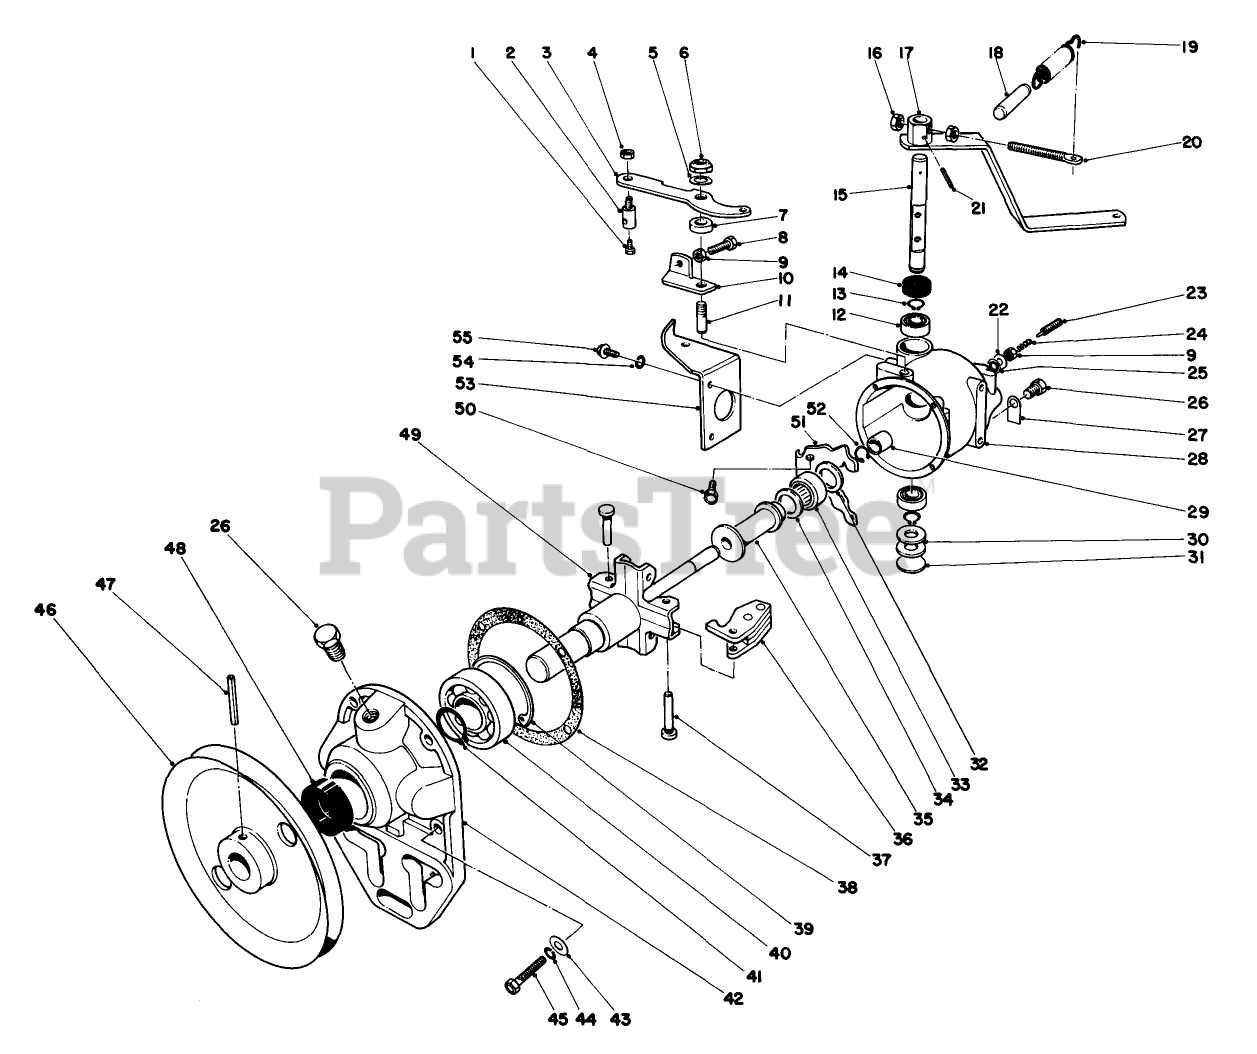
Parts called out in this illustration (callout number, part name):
1	SCREW-HH
2	SWIVEL
3	Speed Change Lever
4	NUT-LOCK, NI
5	WASHER
6	LACKNUT
7	Spacer
8	SCREW-HH
9	NUT-HEX
10	Stop Bracket
12	BALL BRG
13	EXT SNAP RING
14	OIL SEAL
15	Rocker Shaft
16	NUT-HEX
17	THROTTLE LEVER ASM
18	FORCED IDLE PLUG
19	SPRING
20	EYESCREW
21	PIN-ROLL
22	Shim Washer
23	BUMPER SCREW
24	BUMPER SPRING
25	SEALING WASHER
26	PIPE PLUG
27	OIL LEVEL TAG
29	DRIVE SHAFT BUSHING
30	WASHER
31	WELCH PLUG
32	THRUST WASHER
33	THRUST BEARING
34	THRUST WASHER
35	THRUST SLEEVE
36	WEIGHT ASM
37	WEIGHT PIN
38	GASKET
39	INT BEVELED
40	BEARING-BALL
41	RETAINING RING
42	FLANGE
43	WASHER-FLAT
44	WASHER-LOCK
45	10-24 X 7/8 IND HD SC
46	Pulley
47	PIN-SPRING
48	OIL SEAL
49	SPIDER & SHAFT ASM
50	MACHINE SCREW
52	RETAINING RING
53	Bracket
54	WASHER-LOCK
55	SCREW
